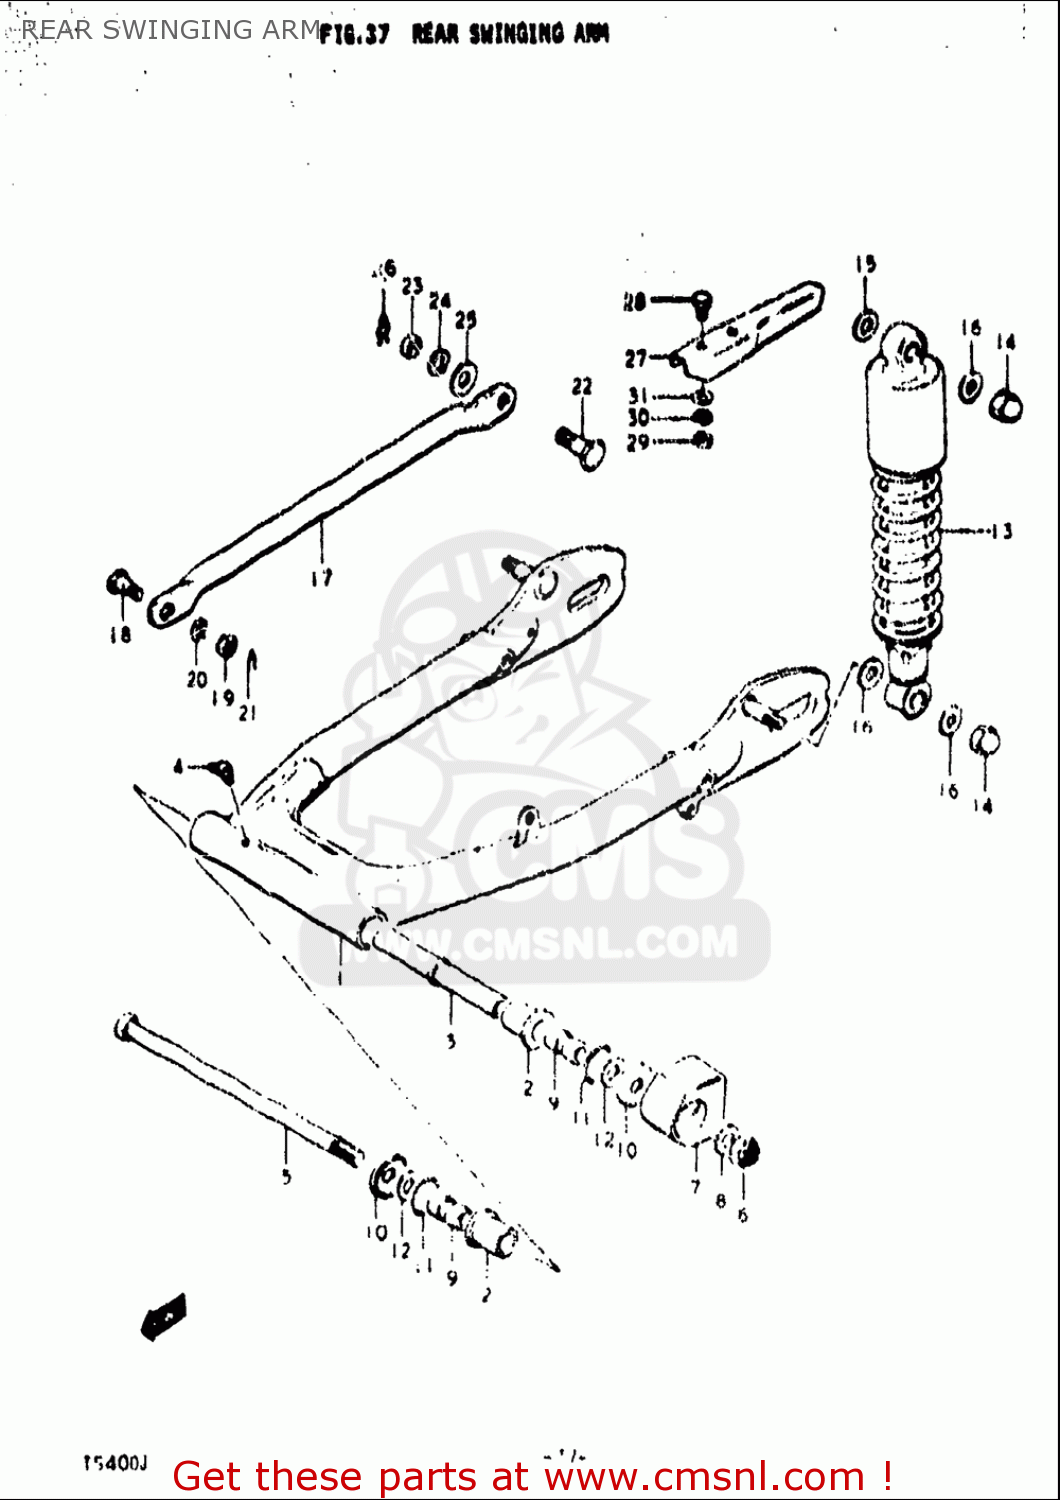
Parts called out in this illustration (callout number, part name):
2	BUSH
3	SPACER,SWING ARM,CENTER
4	NIPPLE,GREASE
8	WASHER
9	SPACER
10	COVER
11	O RING(D:3,ID:29.5)
12	WASHER(14.5X29X2.3)
14	NUT
15	WASHER
16	WASHER (10.5X24X2.3)
19	NUT
20	WASHER,LOCK
21	RETAINER,SNAP
23	NUT
24	WASHER,LOCK
25	WASHER(12.5X24X1.6)
26	SPRING,RETAINER
28	BOLT
29	NUT
30	WASHER,LOCK
